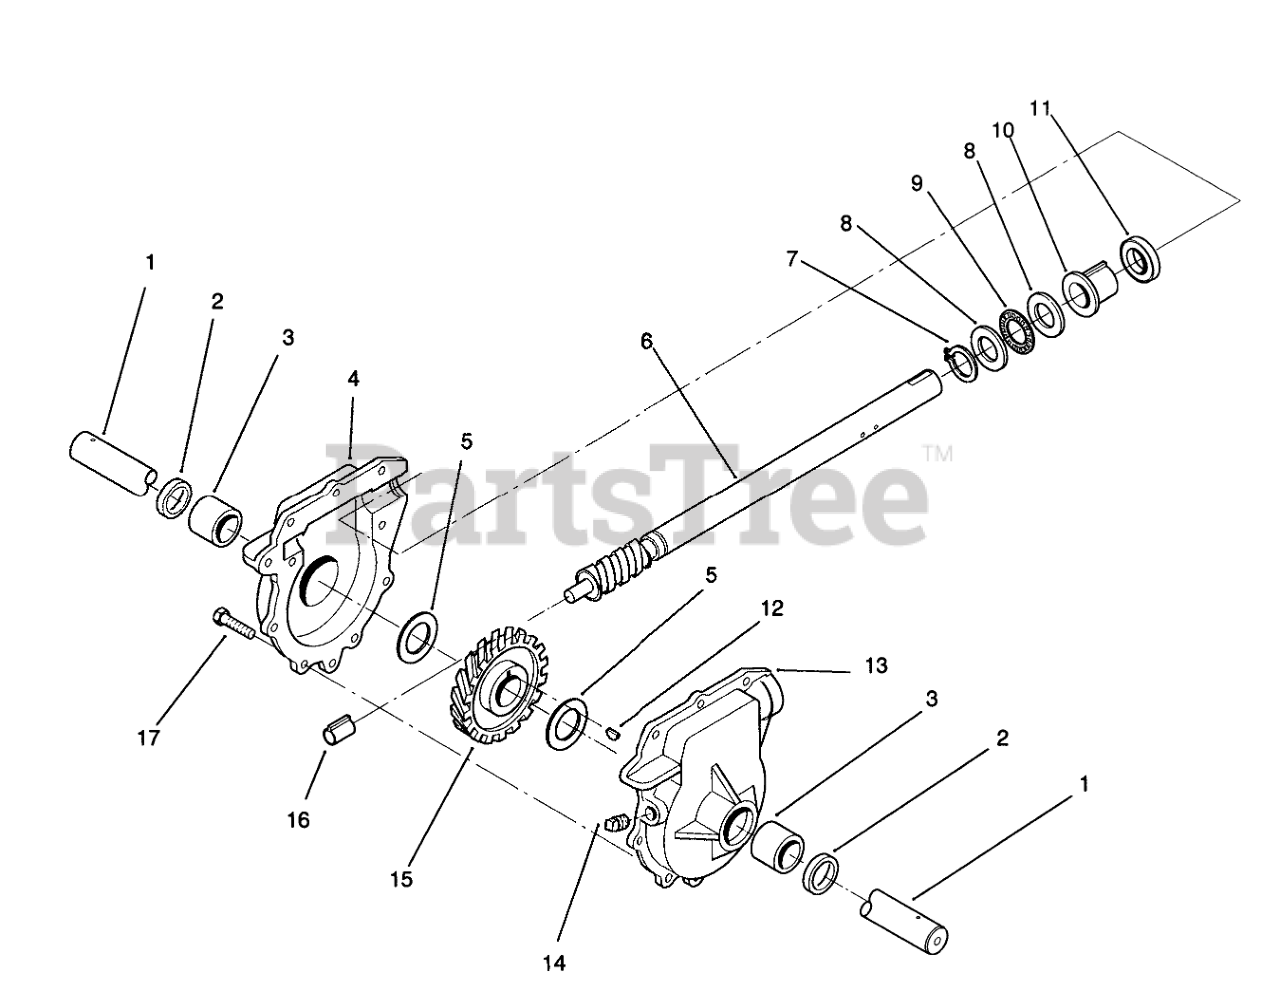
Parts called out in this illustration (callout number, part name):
1	SHAFT-AUGER
2	SEAL-OIL
3	BUSHING
4	Gearcase Assembly-R.H. (Incl. Ref. #2-3)
5	WASHER-THRUST
6	Shaft-Impeller
7	RING-RETAINING, Ext
8	WASHER-THRUST
9	BEARING-THRUST
10	BUSHING-INPUT
11	SEAL-OIL
12	KEY-WOODRUFF
13	Gearcase Assembly-L.H. (Incl. Ref. #2-3)
14	PLUG-PIPE, SQH
15	GEAR-HELICAL
16	BUSHING-WORM
17	SCREW-HWH
